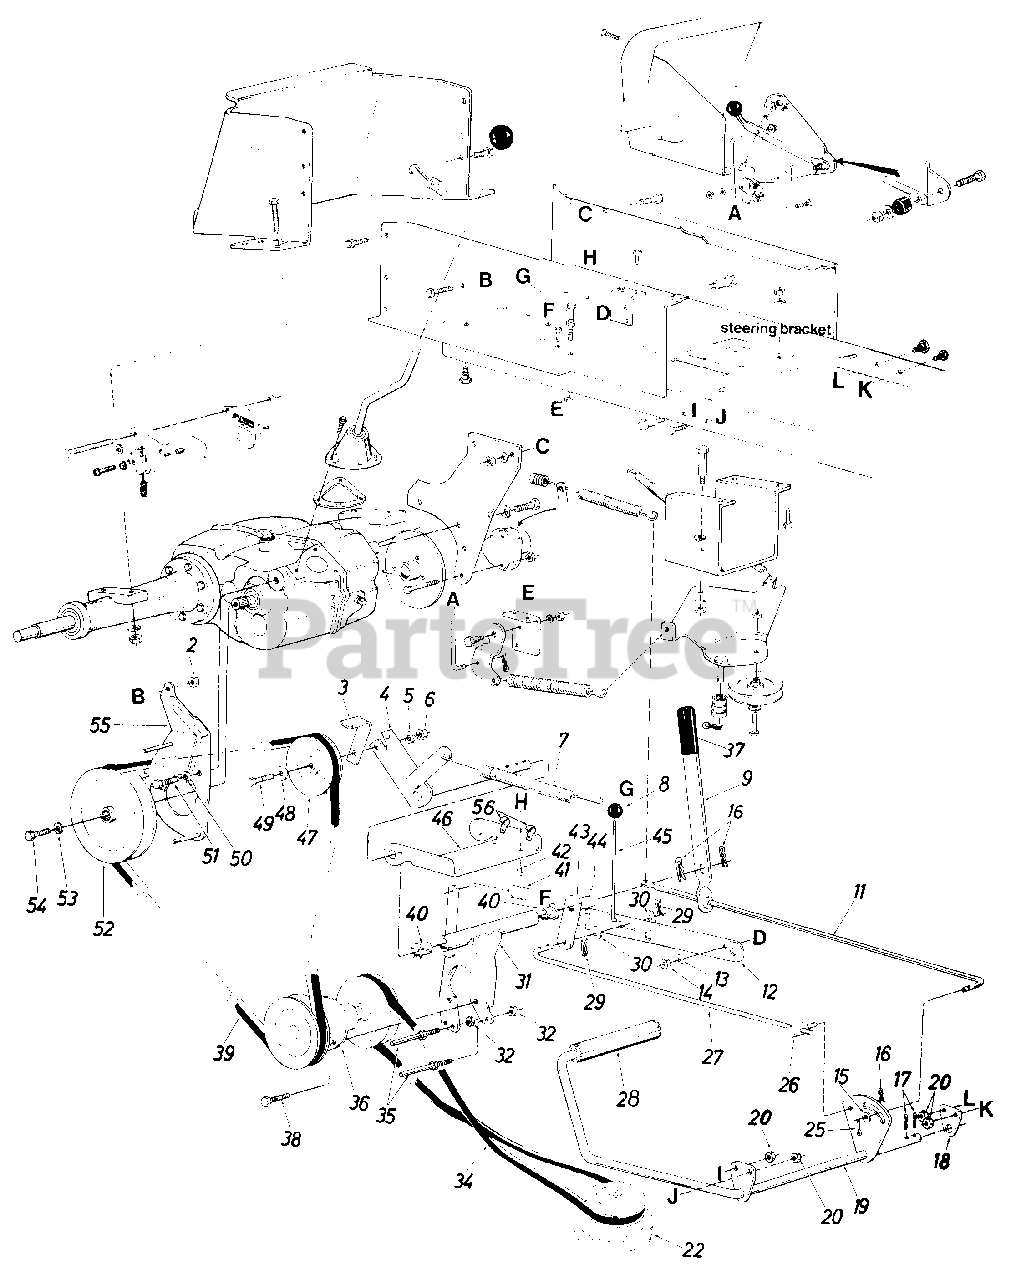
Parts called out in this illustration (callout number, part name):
2	Hex L-Nut 3/8-16 Thd.
3	Belt Guard
4	Clutch Brkt. Ass'y.
5	L-Wash. 3/8" I.D.*
6	Hex Nut 3/8-16 Thd.*
7	Ext. Spring
8	Knob
9	Hand Brake Lever
11	Brake Rod
12	Parking Brake Cam
13	L-Wash. 5/16 I.D.*
14	Hex Nut 5/16-18 Thd.*
15	Fl-Wash. 5/16" I.D.
16	Hairpin Cotter 3/8" Rod
17	Cotter Pin 1/8" Dia. x 1.00" Lg.*
18	Clutch Rod Brg. Brkt.
19	Clutch-Brake Pedal Ass'y.
20	Hex Cent. L-Nut 3/8-16 Thd.*
22	Engine Pulley 4.75 & 5.56
25	Cotter Pin 3/32" Dia. x .75" Lg. *
26	Pivot Bushing
27	Brake Cam Rod
28	Foot Pad
29	Hairpin Cotter 3/8" Rod
30	Fl-Wash. 3/8" I.D. x 1.00" O.D. x .030
31	Jack Shaft Mtg. Brkt. Ass'y.
32	Hex Top L-Nut 3/8-16 Thd.
34	"V"-Belt
35	Stud 3/8-16 x 3.62" Lg.
36	Jack Shaft Ass'y.
37	Flat Grip
38	Hex Sem Scr. 5/16-18 x .75" Lg.*
39	"V"-Belt
40	Nyliner 518" I.D. x .88" Lg.
41	Ext. Spring
42	Hex Thd. Rolling Scr. 1/4-20 x .50" Lg.
43	Clutch-ldler Horn Ass'y.
44	Spring Pin Spiral 1/4" Dia. x 1.00" Lg.
45	Parking Brake Link
46	Idler Mtg. Brkt.-Drive
47	4" "V"-ldler Pulley
48	Fl-Wash. 3/8" I.D.
49	Hex Bolt 3/8-16 x 1.75" Lg.
50	L-Wash. 3/8" I.D.
51	Hex Bolt 3/8-16 x .75" Lg.
52	"V"-Pulley 7.0" O.D.
53	L-Wash. 3/8" I.D.
54	Hex Scr. 3/8-24 x .75" Lg.
55	Belt Guard Ass'y.
56	Plastic Hose Clamp
